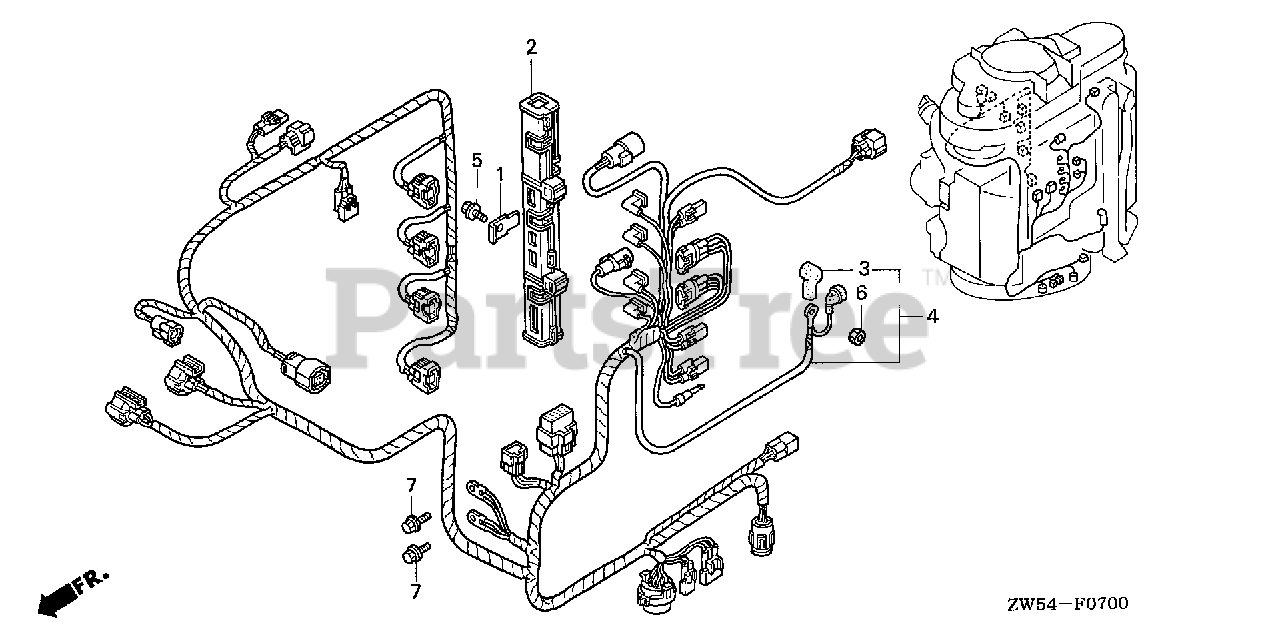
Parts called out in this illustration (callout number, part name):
1	BRACKET, CONNECTOR (C)
2	HOLDER A, HARNESS
3	COVER A, MAGNETIC SWITCH
4	CABLE ASSY., REMOTE CONTROL (A)
5	BOLT, FLANGE (6X12)
6	NUT, HEX. (6MM)
7	BOLT, FLANGE (6X14)
